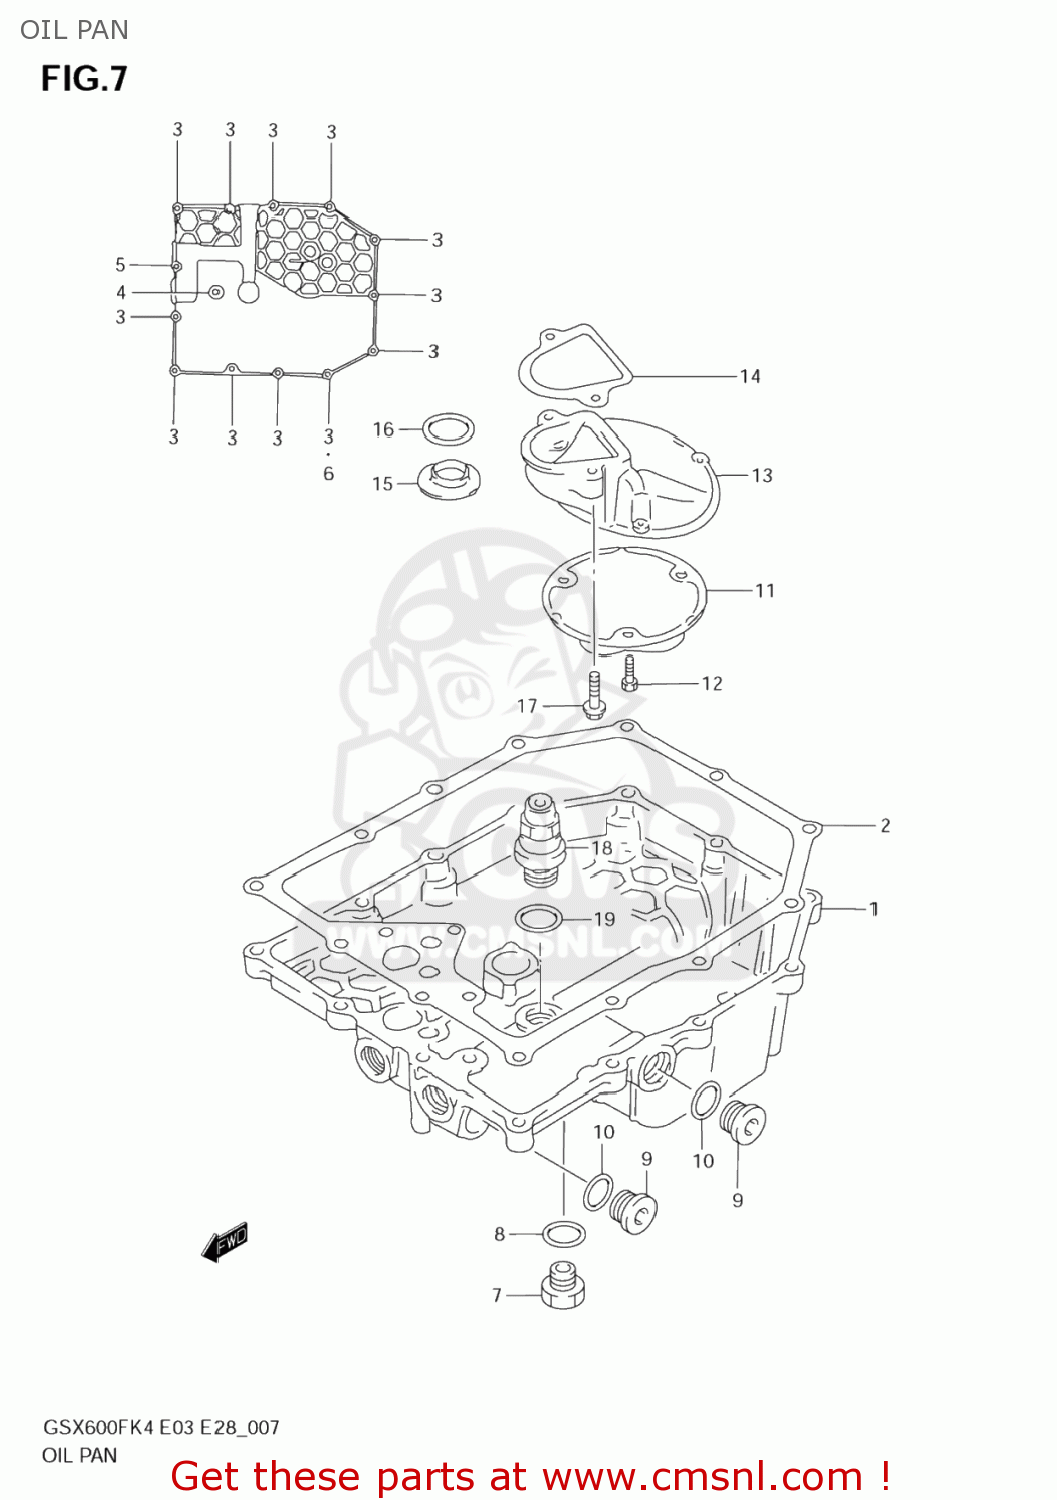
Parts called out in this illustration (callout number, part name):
1	PAN,OIL
2	GASKET,OIL PAN(ASB) (NAS)
3	BOLT
4	BOLT
5	BOLT
6	GASKET(5.8X13X1.2) (NAS)
7	PLUG(14X12)
8	GASKET(13.8X18.8X4.8) (NAS)
9	PLUG,16X8
10	GASKET(16X22X2) (NAS)
11	STRAINER,ENGINE OIL
12	BOLT
13	PROTECTOR,OIL STRAINER
14	GASKET,OIL STR PROTECTOR (NAS)
15	GASKET,OIL OUTLET (NAS)
16	O RING(D:3.2,ID:17.8)
17	BOLT
18	VALVE ASSY,OIL RELIEF
19	GASKET(16X22X2) (NAS)
